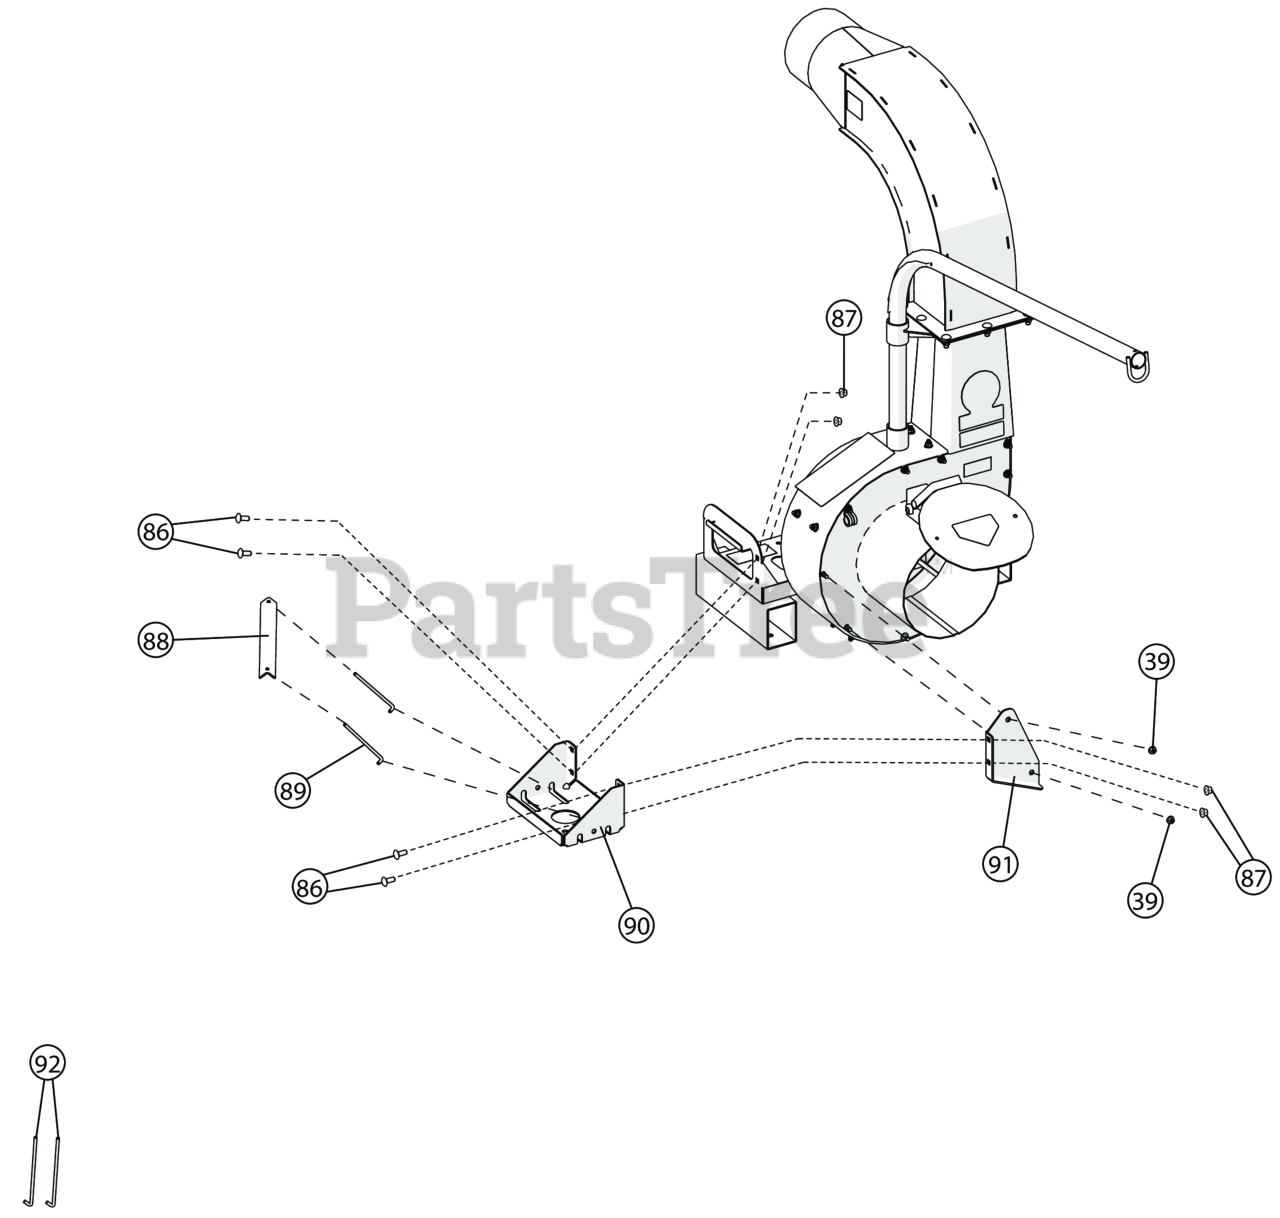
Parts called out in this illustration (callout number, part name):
39	NUT FLANGE 5/16"-18 ZP
86	BOLT CARRAIGE 3/8-16 X 1" ZP
87	NUT-HEX-NYLK, FLG .375"-16 ZP
88	BRACKET BATTERY
89	ROD BATTERY HOLD DOWN 6"
90	TRAY BATTERY DL18
91	BRACKET MOUNT TRAY BATTERY DL18
92	ROD BATTERY HOLD DOWN
